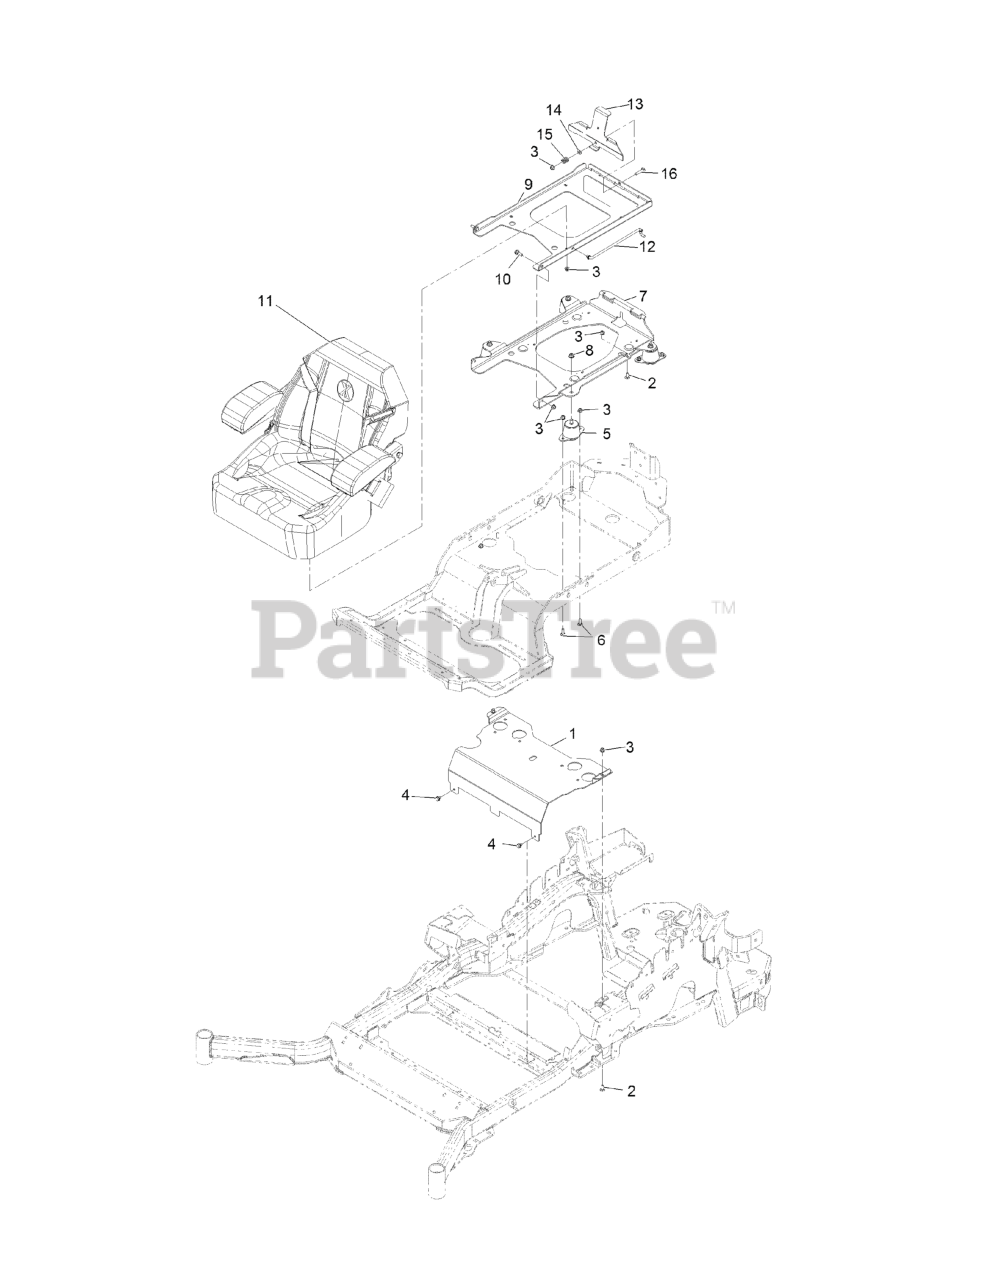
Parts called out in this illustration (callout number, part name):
1	Panel-Front, Seat Mount
2	SCREW-CARR
3	NUT-HF, NI
5	ISOLATOR-SEAT
6	BOLT-CARR
7	PLATE-SUPPORT, ISO SEAT
8	NUT-HF, NI
9	PLATE-FRAME, SEAT
10	SCREW-SHOULDER
11	SEAT-EXMARK STANDARD
12	ROD-PROP
13	PLATE-LATCH,SEAT
14	WASHER-PLAIN
15	SPRING-COMPRESSION
16	BOLT-CARR
